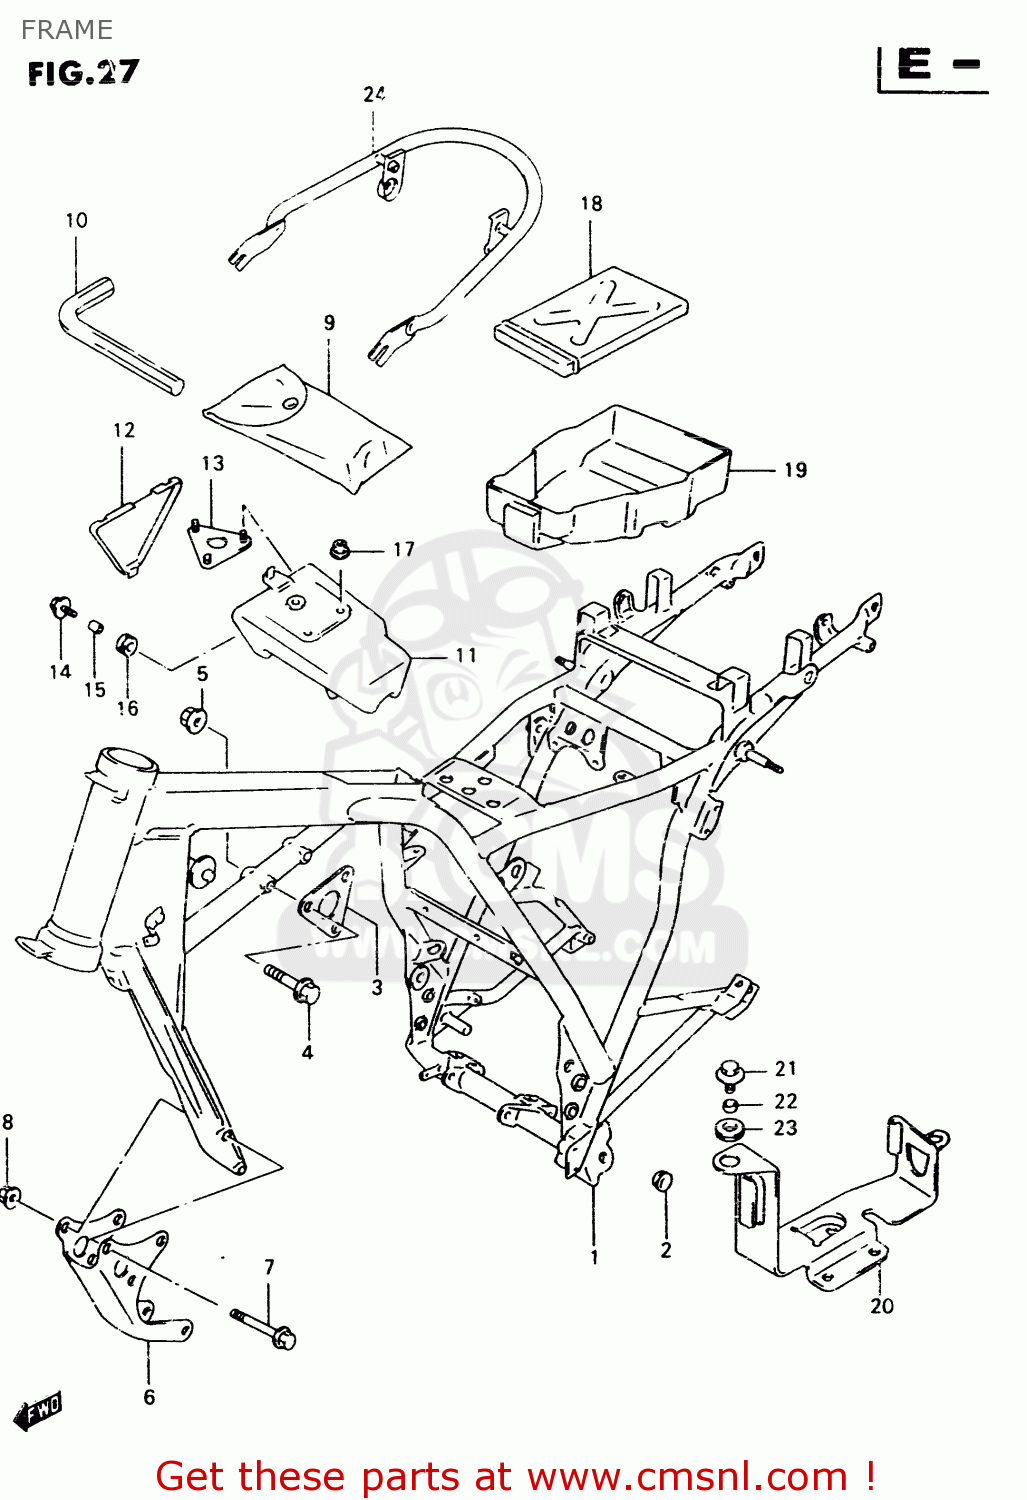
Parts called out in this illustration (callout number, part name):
1	FRAME(BLACK)
2	PLUG(OD:19)
3	PLATE,ENGINE MOUNT UPR
4	BOLT(8X50)
5	NUT
6	PLATE,ENGINE MOUNTING
7	BOLT
8	NUT
9	TOOL ASSY
10	HEXAGON SPANNER,12
11	BOX,TOOL
12	CAP,TOOL BOX
13	PLATE,TOOL HOLDER
14	BOLT(6X16)
15	SPACER(6.1X9X7.5)
16	CUSHION
17	NUT
18	BOX ASSY,OWNER'S MANUAL
19	BOX,LUGGAGE
20	HOLDER,BATTERY
21	BOLT(6X16)
22	SPACER(6.1X9X7.5)
23	CUSHION
24	HANDLE, PILLION RIDER
